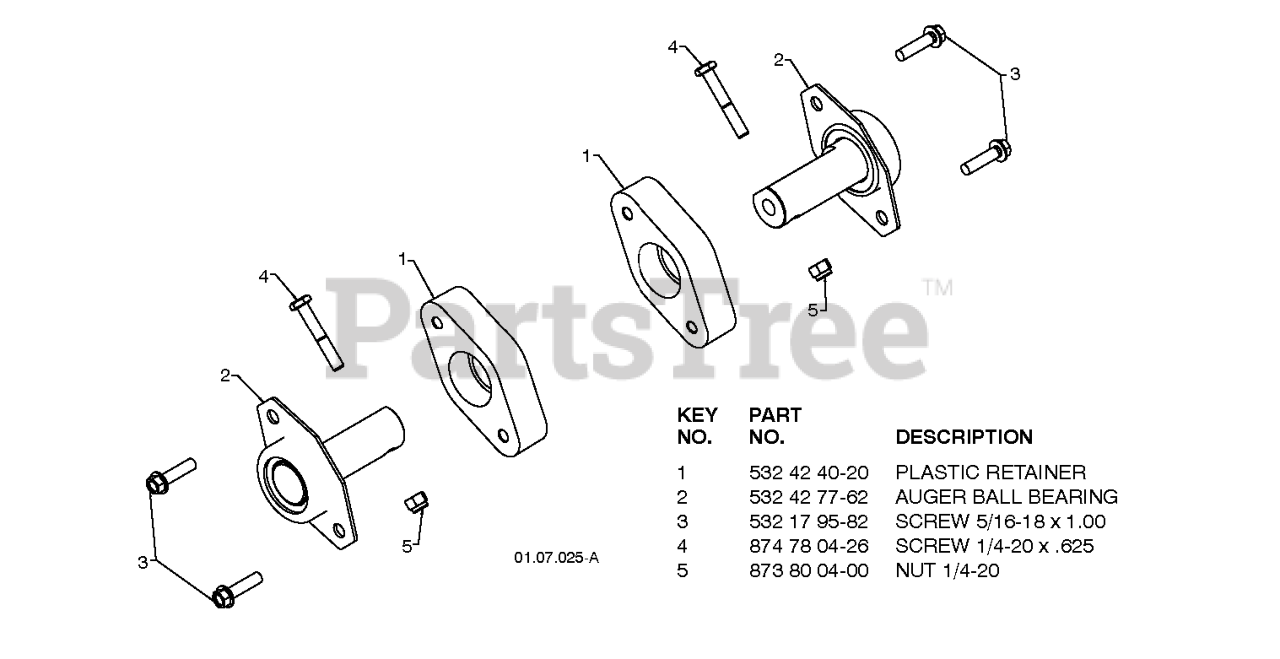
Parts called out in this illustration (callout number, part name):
1	RETAINER.PLASTIC
2	BEARING.BALL.AUGER.FLAT.
3	SCREW, HEX HD 5/16X1
4	SCREW.HEX.HD1/4-20X
5	LOCKNUT.NYLOC.1/4-20
